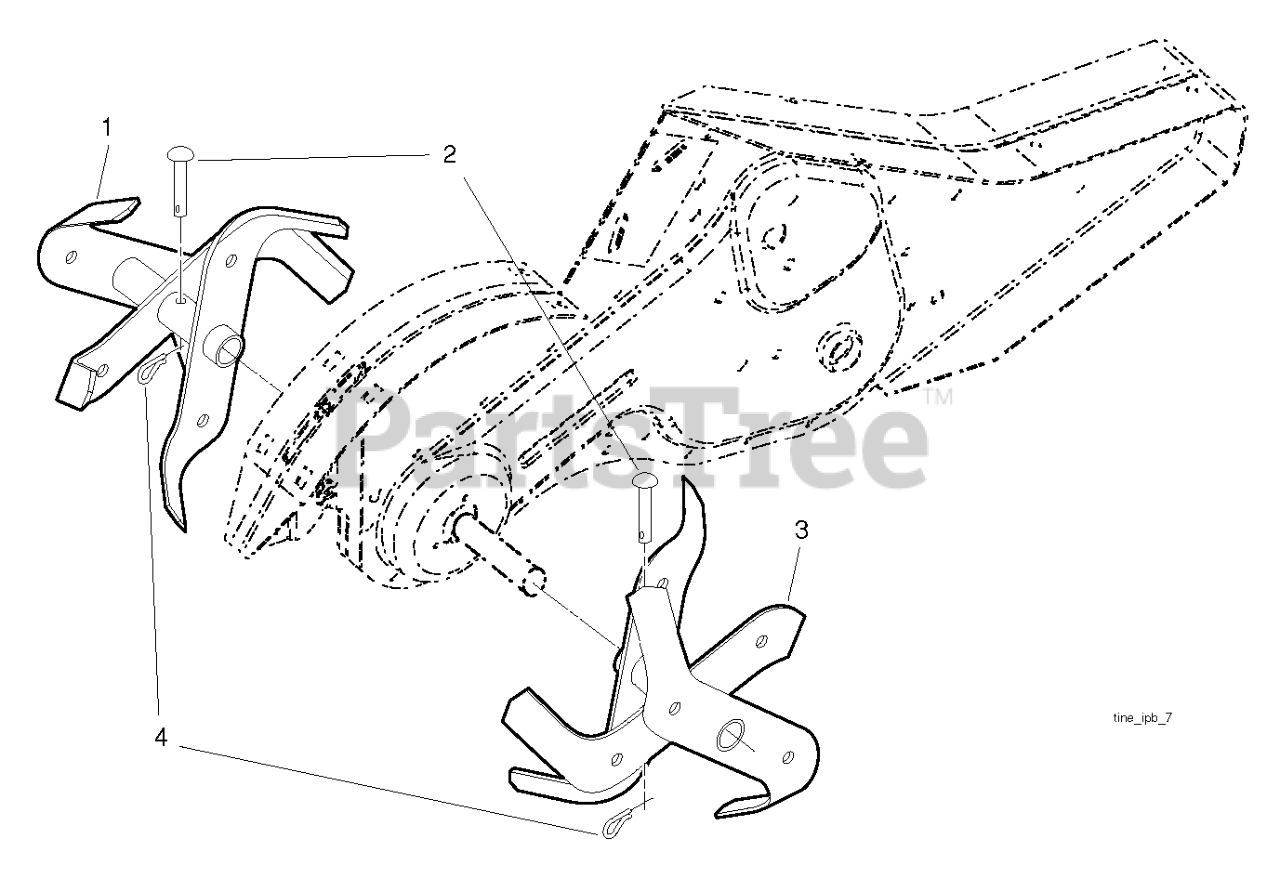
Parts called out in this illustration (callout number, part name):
1	TINE.ASM.LH.TILLER.BLACK
2	PIN RETAINING SCREW
3	TINE.ASM.RH.PNT.479
4	SPRING RETAINER
